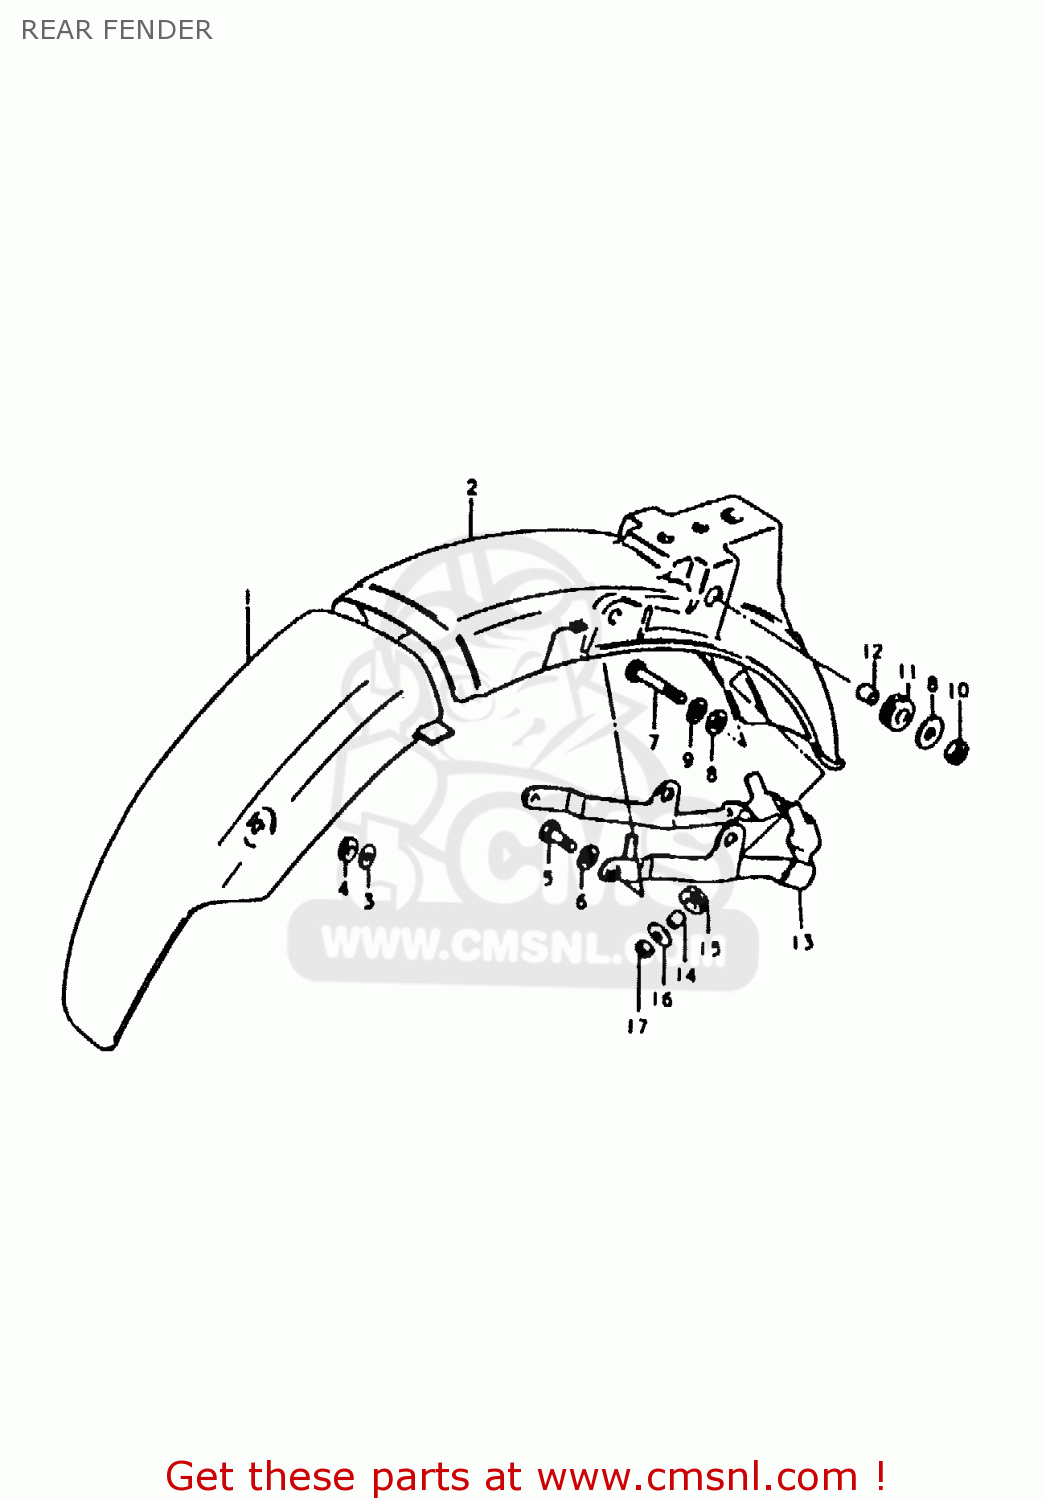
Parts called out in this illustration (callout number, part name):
1	BODY, REAR FENDER FRONT
2	FENDER, REAR
3	WASHER
4	CUSHION
5	BOLT, UPPER
6	LOCK WASHER
7	BOLT
8	WASHER
9	LOCK WASHER
10	NUT
11	CUSHION
12	SPACER (8.2X12X7.5)
13	REINFORCEMENT
14	SPACER (6.1X9X9)
15	CUSHION
16	WASHER(6,5X22X1.6)
17	NUT
